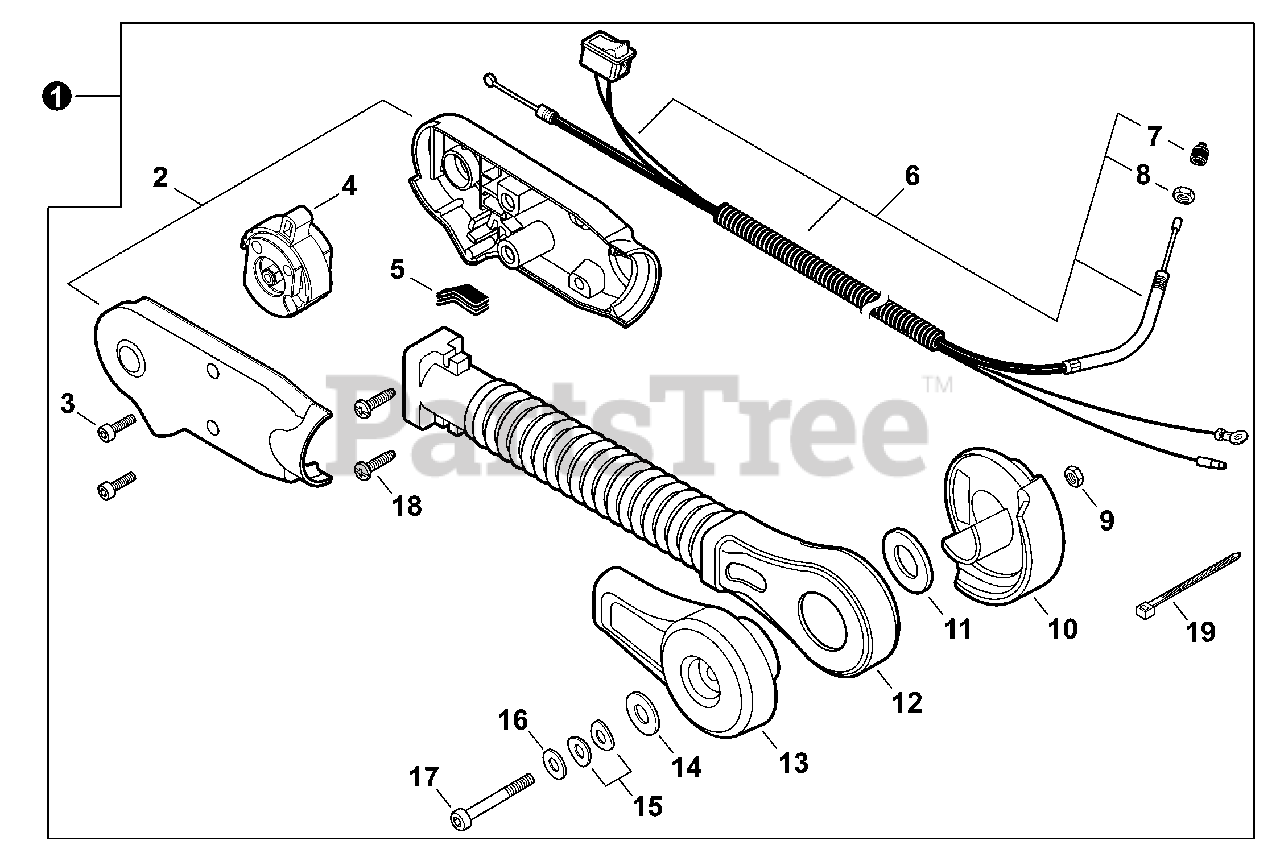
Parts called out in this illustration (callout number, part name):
1	THROTTLE CONTROL KIT - HIP MOUNT
2	GRIP SET, THROTTLE
3	BOLT, TORX 5×16
4	CONTROL, THROTTLE
5	GROMMET
6	CABLE ASSY, CONTROL
7	CAP, DUST
8	NUT, HEX M6
9	NUT, LOCK M6
10	BRACKET, ARM - INNER
11	WASHER 45
12	ARM, THROTTLE CONTROL
13	BRACKET, ARM - OUTER
14	WASHER 6.6×20×1.6
15	WASHER, FRICTION 6.6×14.3
16	WASHER 6.5×15.5×0.6
17	BOLT, TORX 6×75
19	STRAP, TIE
